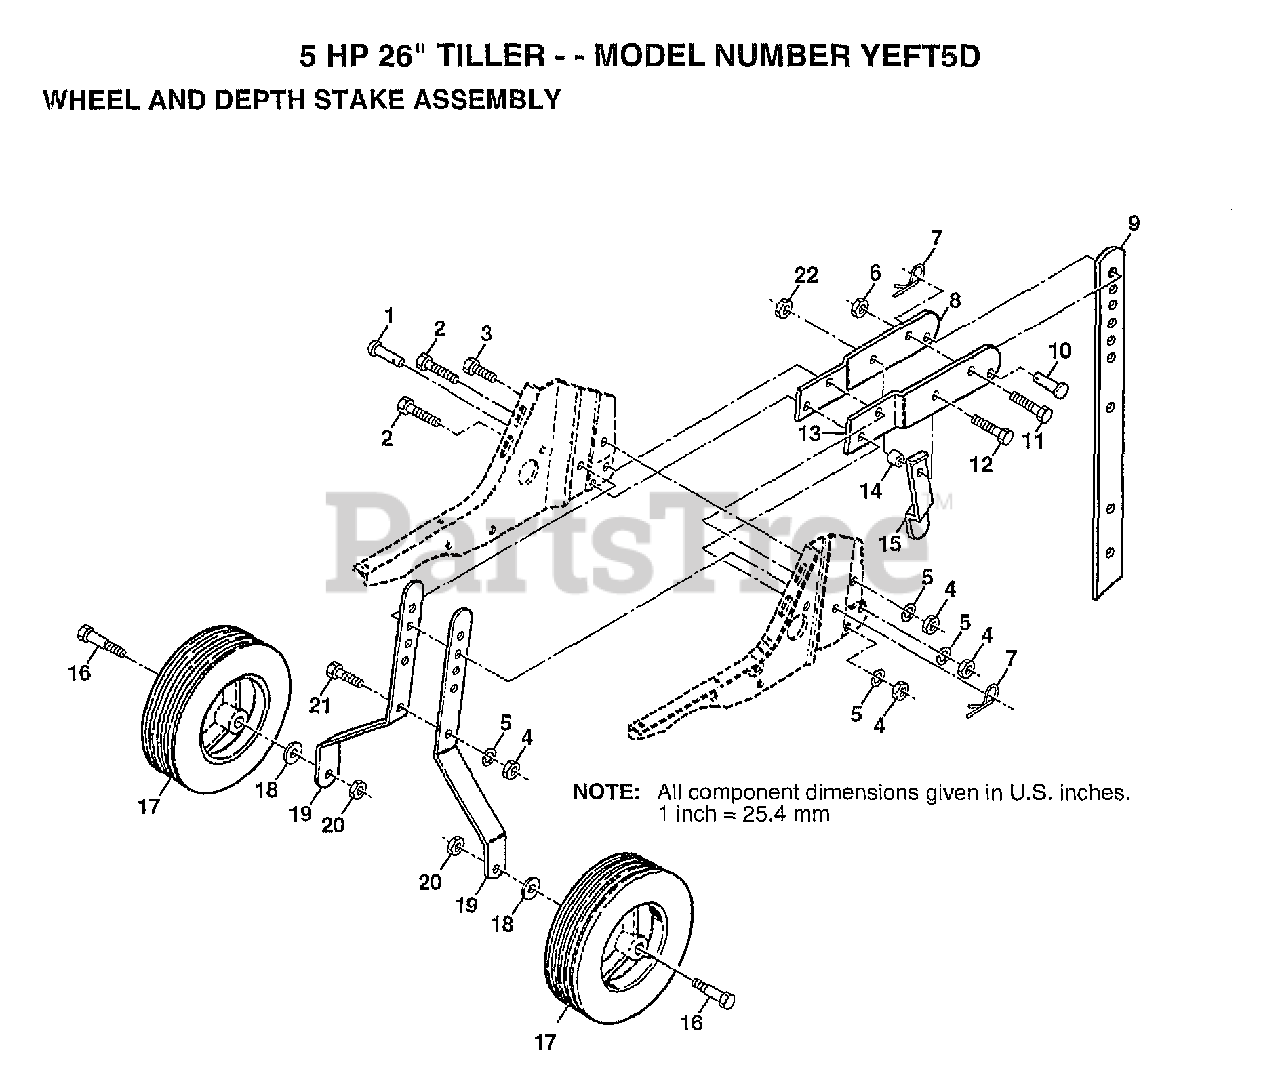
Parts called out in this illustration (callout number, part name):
1	DRILLED RIVET RT
3	BOLT
4	NUT.HEX.5/16-18
5	LOCKWASHER
6	NUT
7	SPRING.RETAINER
8	SUPPORT STAKE RH
11	BOLT
12	BOLT.HEX.5/16-1.5
13	SUPPORT STAKE LH
14	WASHER
15	STAKE SPRING TI
16	BOLT SHOULDER
17	WHEEL TI
18	WASHER
19	BRACKET.WHL.PNT.
22	NUT
